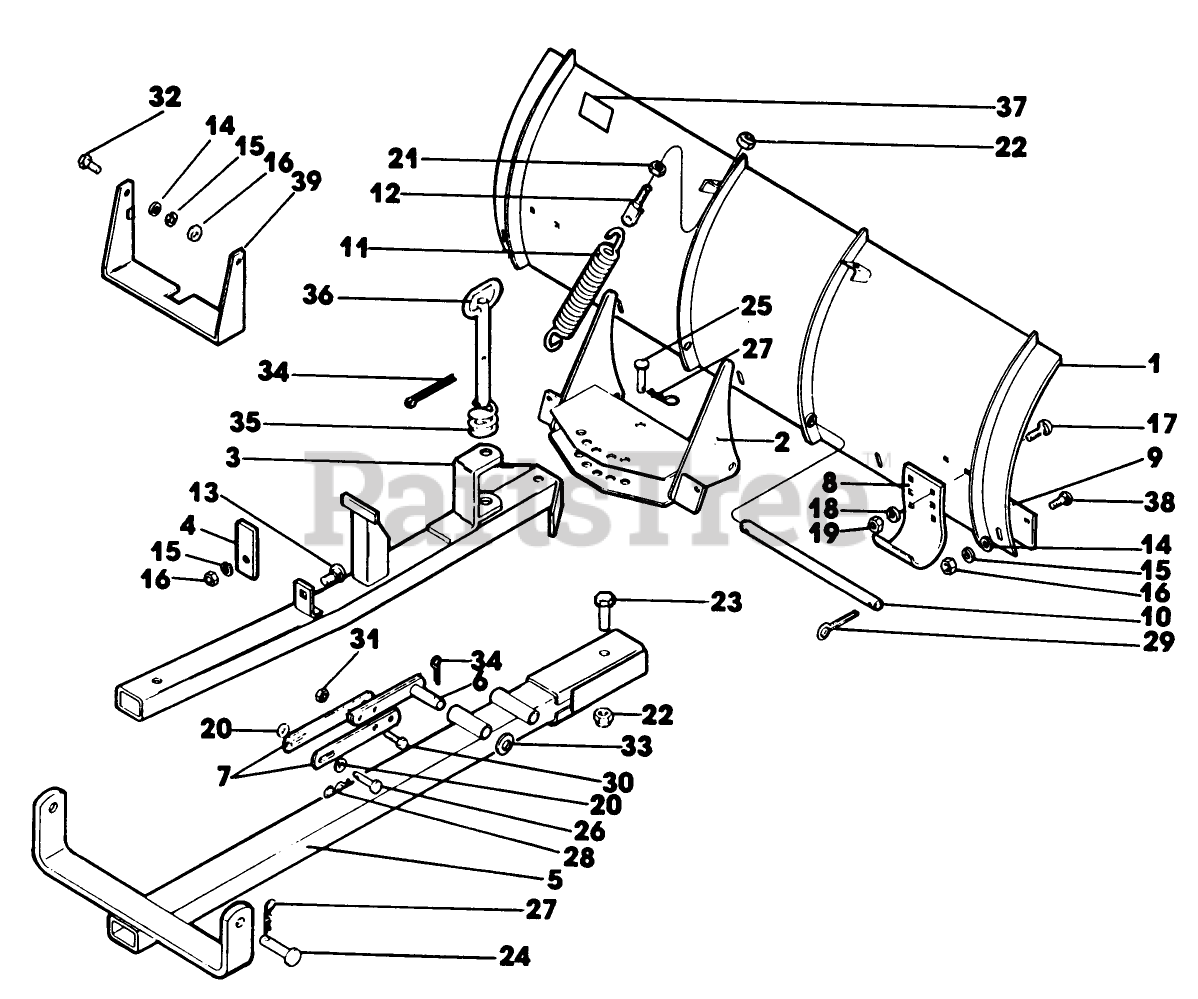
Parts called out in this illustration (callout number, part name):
9	BLADE SCRAPPER
22	NUT-HEX CONE LOK
25	PIN-CLEVIS
28	PIN - SPRING CLIP
31	NUT-HEX
39	STABILIZER
